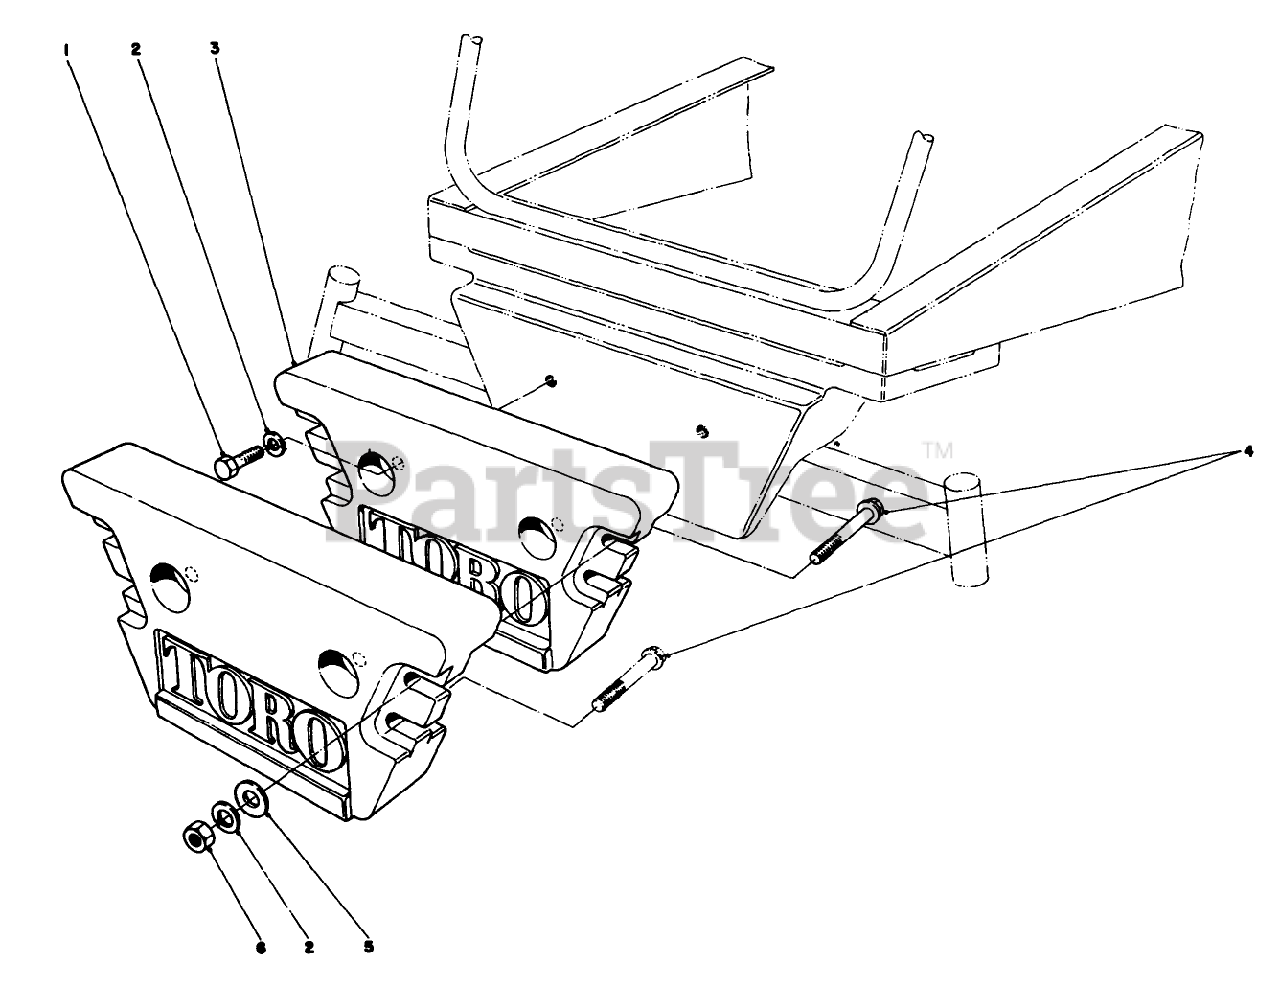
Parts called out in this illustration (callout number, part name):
1	SCREW-HH
2	WASHER-LOCK
3	Rear Weight
4	SCREW-HH
5	WASHER-FLAT
6	NUT-HH
